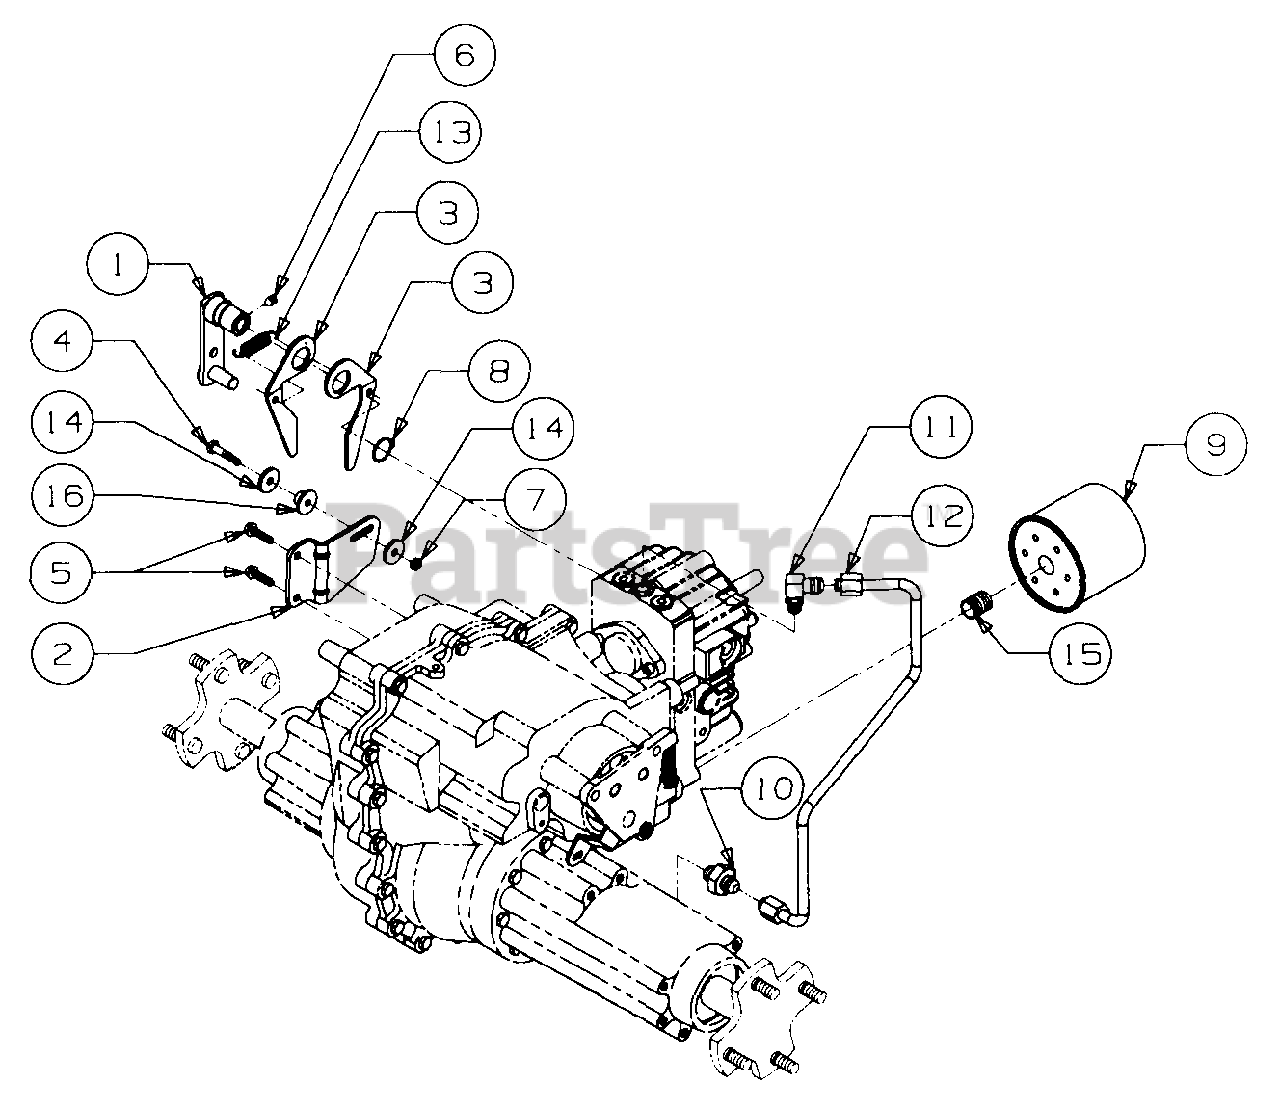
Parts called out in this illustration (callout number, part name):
1	Arm Assy, Control
2	Bracket, Hydro Neutral
3	Arm, Neutral
4	Screw, Hex Cap, 1/4-20 X 1.25 Lg
5	Screw, Hex Wash TT-Tap, 1/4-20 X 1.0 Lg
6	Screw w/Patch, Set
7	Nut, Hex Top Lock, 1/4-20
8	Ring, Snap, .875 Shaft
9	Filter, Oil
10	Connector, Tube 37 Deg w/O-Ring
11	Elbow, Adjustable w/O-Ring
12	Tube, Pickup
13	Spring, Extension, .50 OD X 1.97 Lg
14	Washer, Flat, .25 X .93 X .120 Thk
15	Nipple, Oil Filter
16	Spacer, Centering
